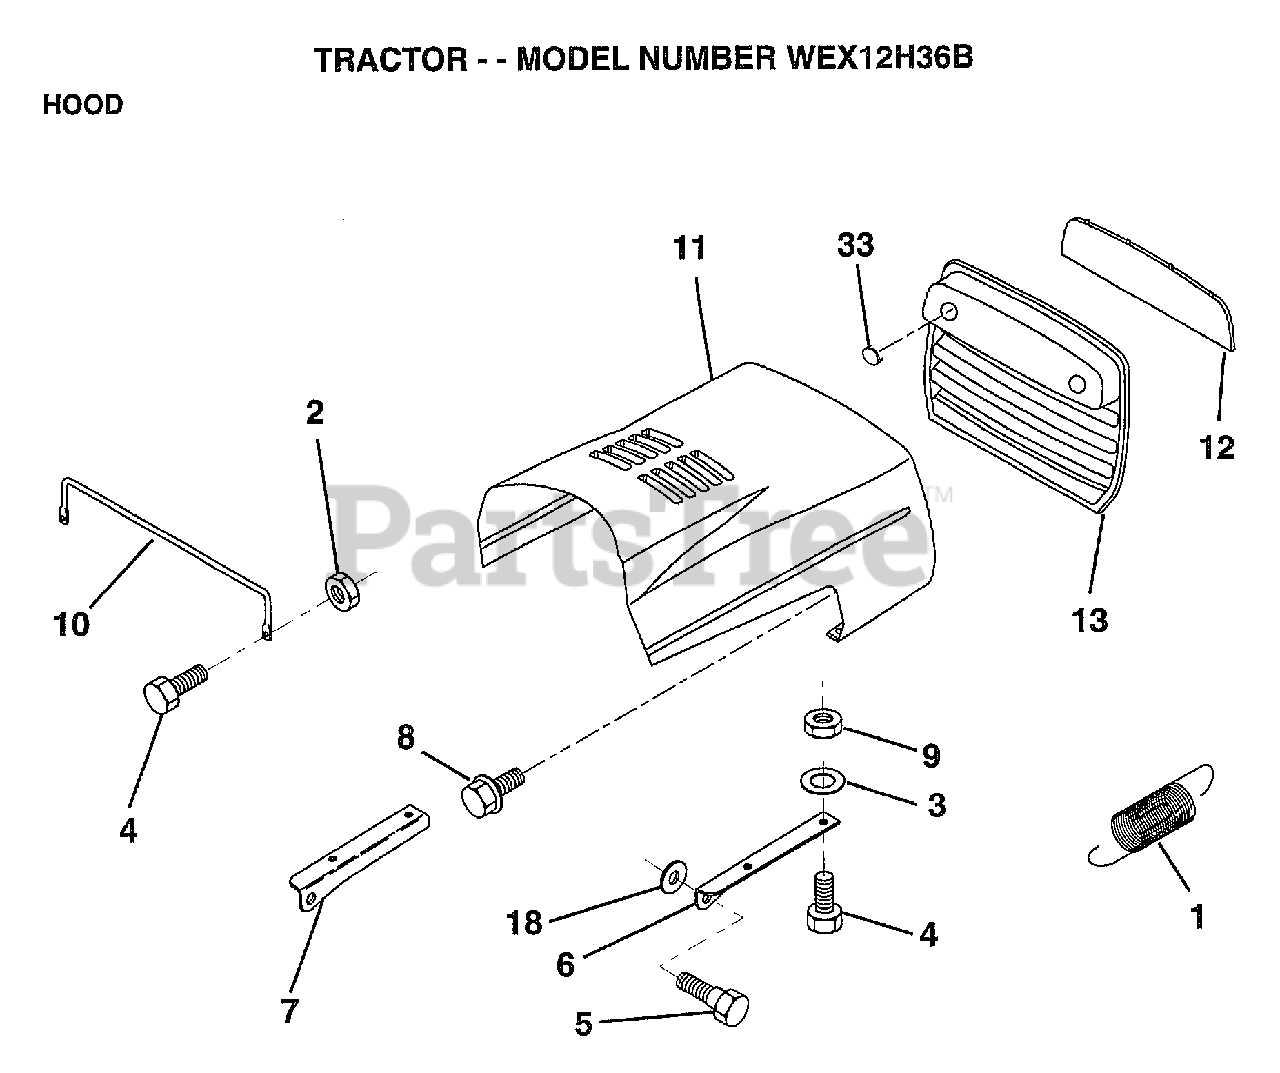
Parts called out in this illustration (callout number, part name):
1	EXT SPRING
2	NUT
3	WASHER
5	BOLT.SHLD.5/16-18
6	BRKT HOOD RH
7	BRKT HOOD LH
8	SCREW SLTD HXHD
9	NUT
10	"BRACE,HOOD"
11	HOOD.IMPREG.MS550
12	LENS
13	GRILL
18	WASHER
